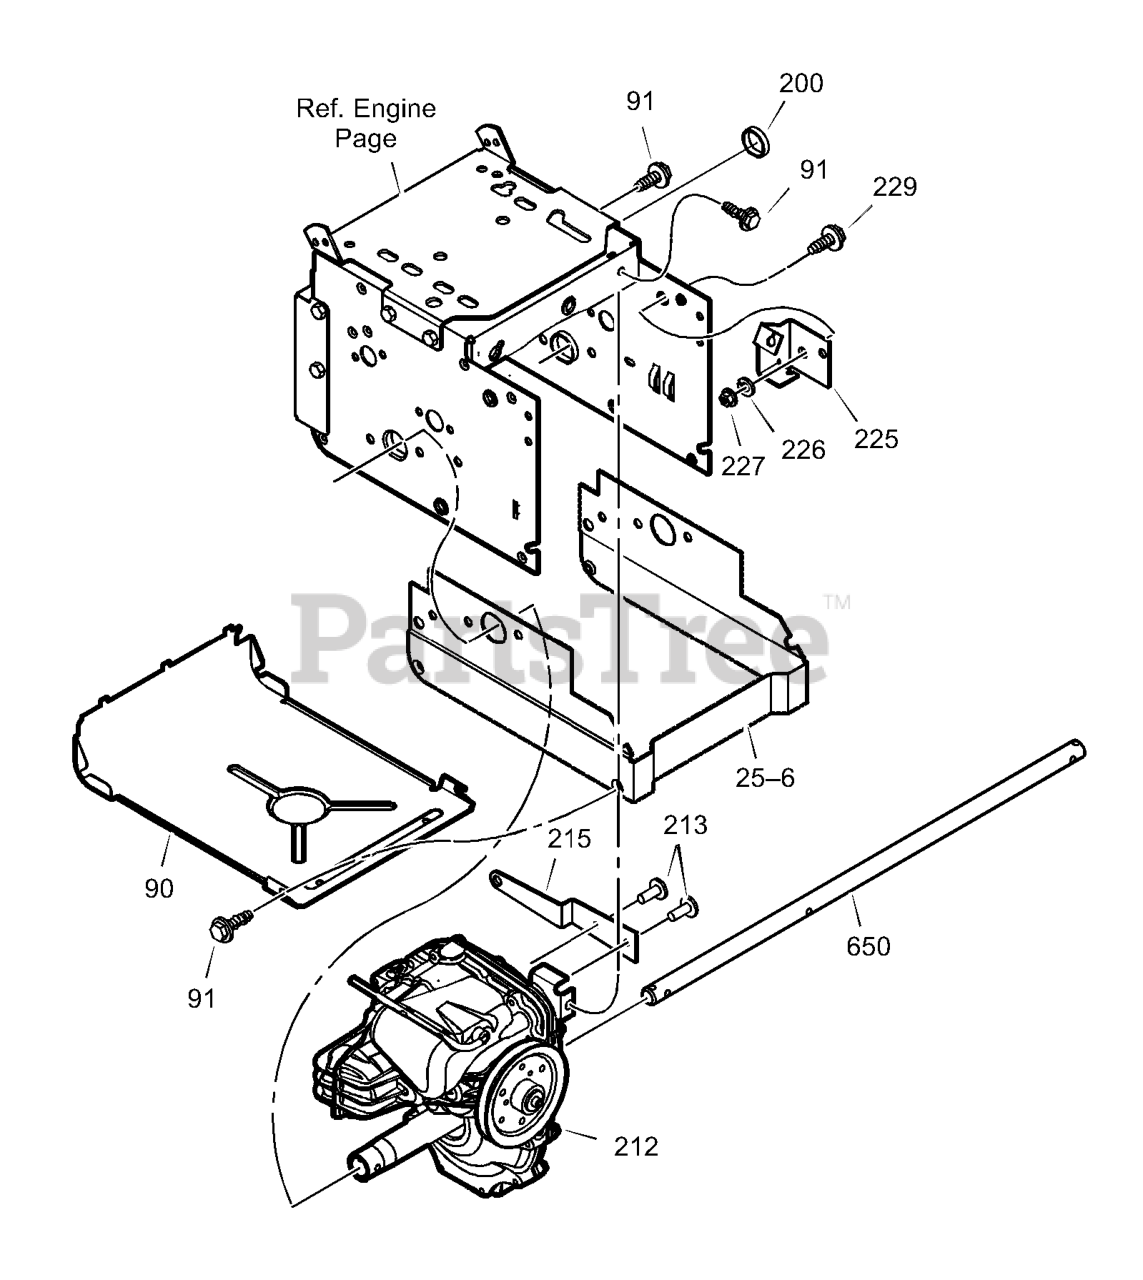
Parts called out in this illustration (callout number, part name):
25-6	FRAME, EXTENSION - HYDRO
90	COVER, BOTTOM
91	SCREW, 1/4-20 X 0.62
200	PLUG, HEYCO
212	Transmission Hydro Gear *
213	RIVET, BLIND
215	ARM, CONTROL EXTENSION
225	BRACKET, DRIVE CABLE
226	WASHER, LOCK
227	NUT, HEX JAM - 3/8-16
229	SCREW
650	AXLE, WHEEL
